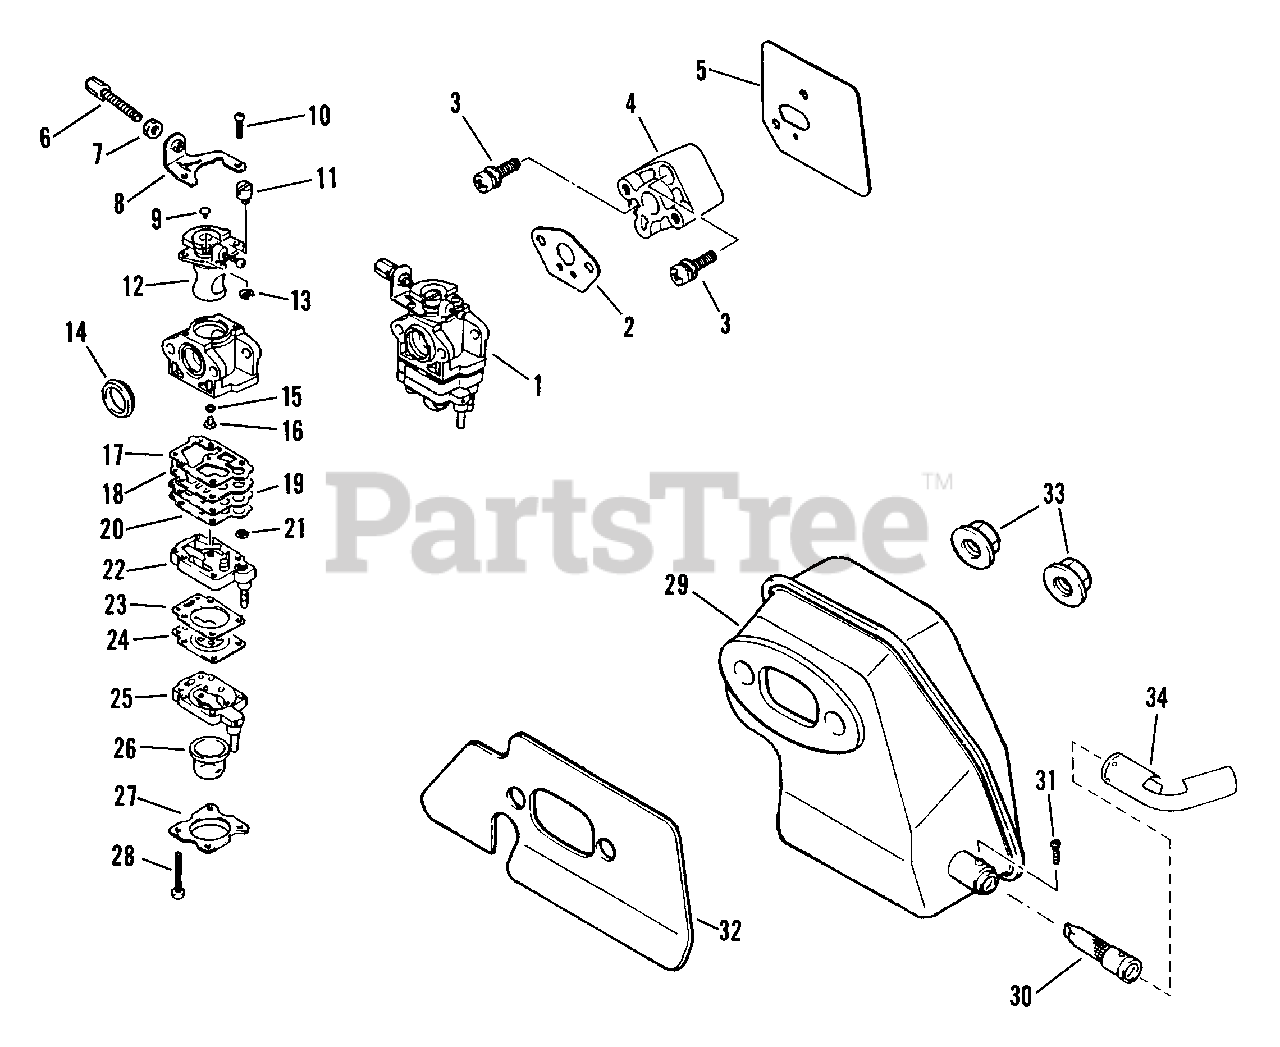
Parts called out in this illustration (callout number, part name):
1	ASSEMBLY, Carburetor
2	GASKET, Carburetor
3	SCREW/WASHER
4	INSULATOR
5	GASKET, Insulator
7	NUT
8	BRACKET
11	HOLDER, Wire
12	VALVE, Throttle
14	PACKING
16	JET, Main
18	DIAPHRAGM
22	BODY, Pump
24	DIAPHRAGM
26	ASSEMBLY, Primer Pump
29	MUFFLER
30	SPARK ARRESTER
32	GASKET, Muffler
33	NUT, Flange
34	EXHAUST, Elbow
